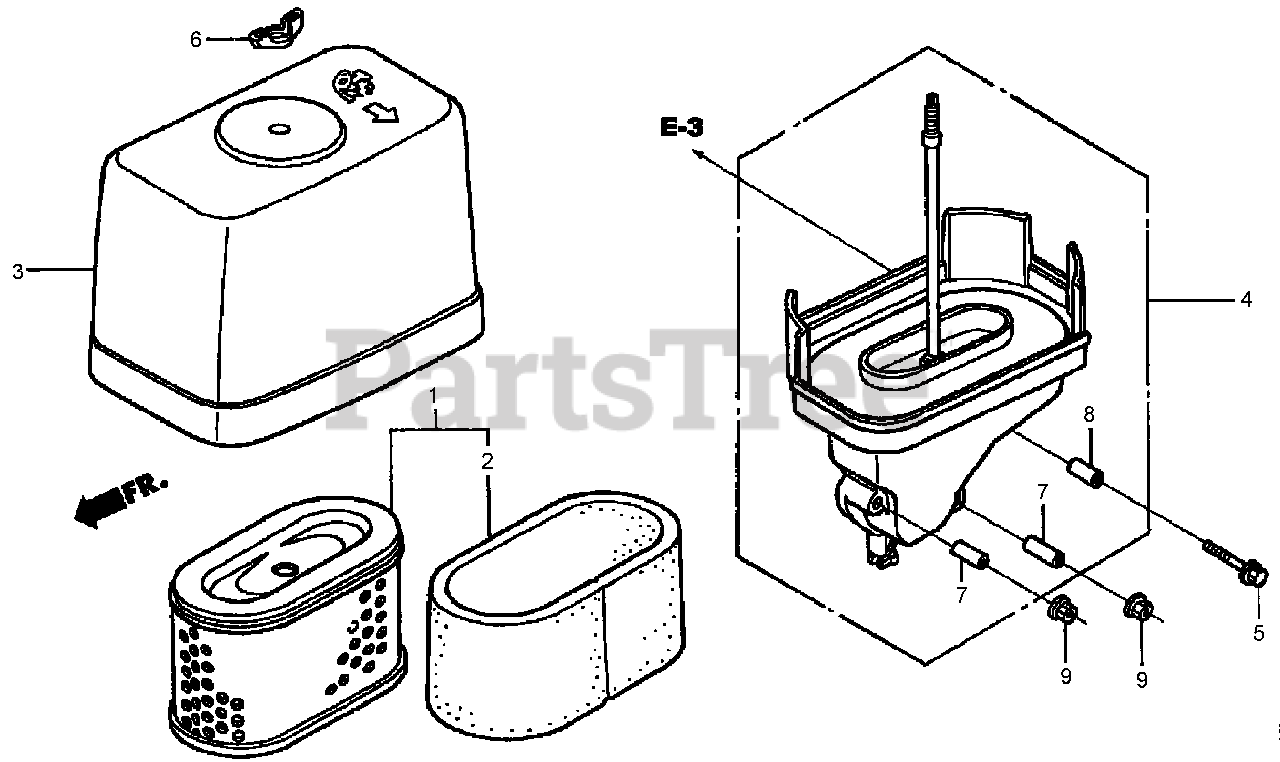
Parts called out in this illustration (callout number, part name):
1	ELEMENT-CLEANER, AIR (PLASTIC BASE)
2	FILTER (OUTER)
3	COVER-CLEANER, AIR
4	ELBOW-CLEANER, AIR
5	BOLT- FLANGE (6X35)
6	WINGNUT
7	COLLAR-CLEANER, AIR
8	COLLAR-CLEANER, AIR
9	NUT-FLANGE (6 mm)
